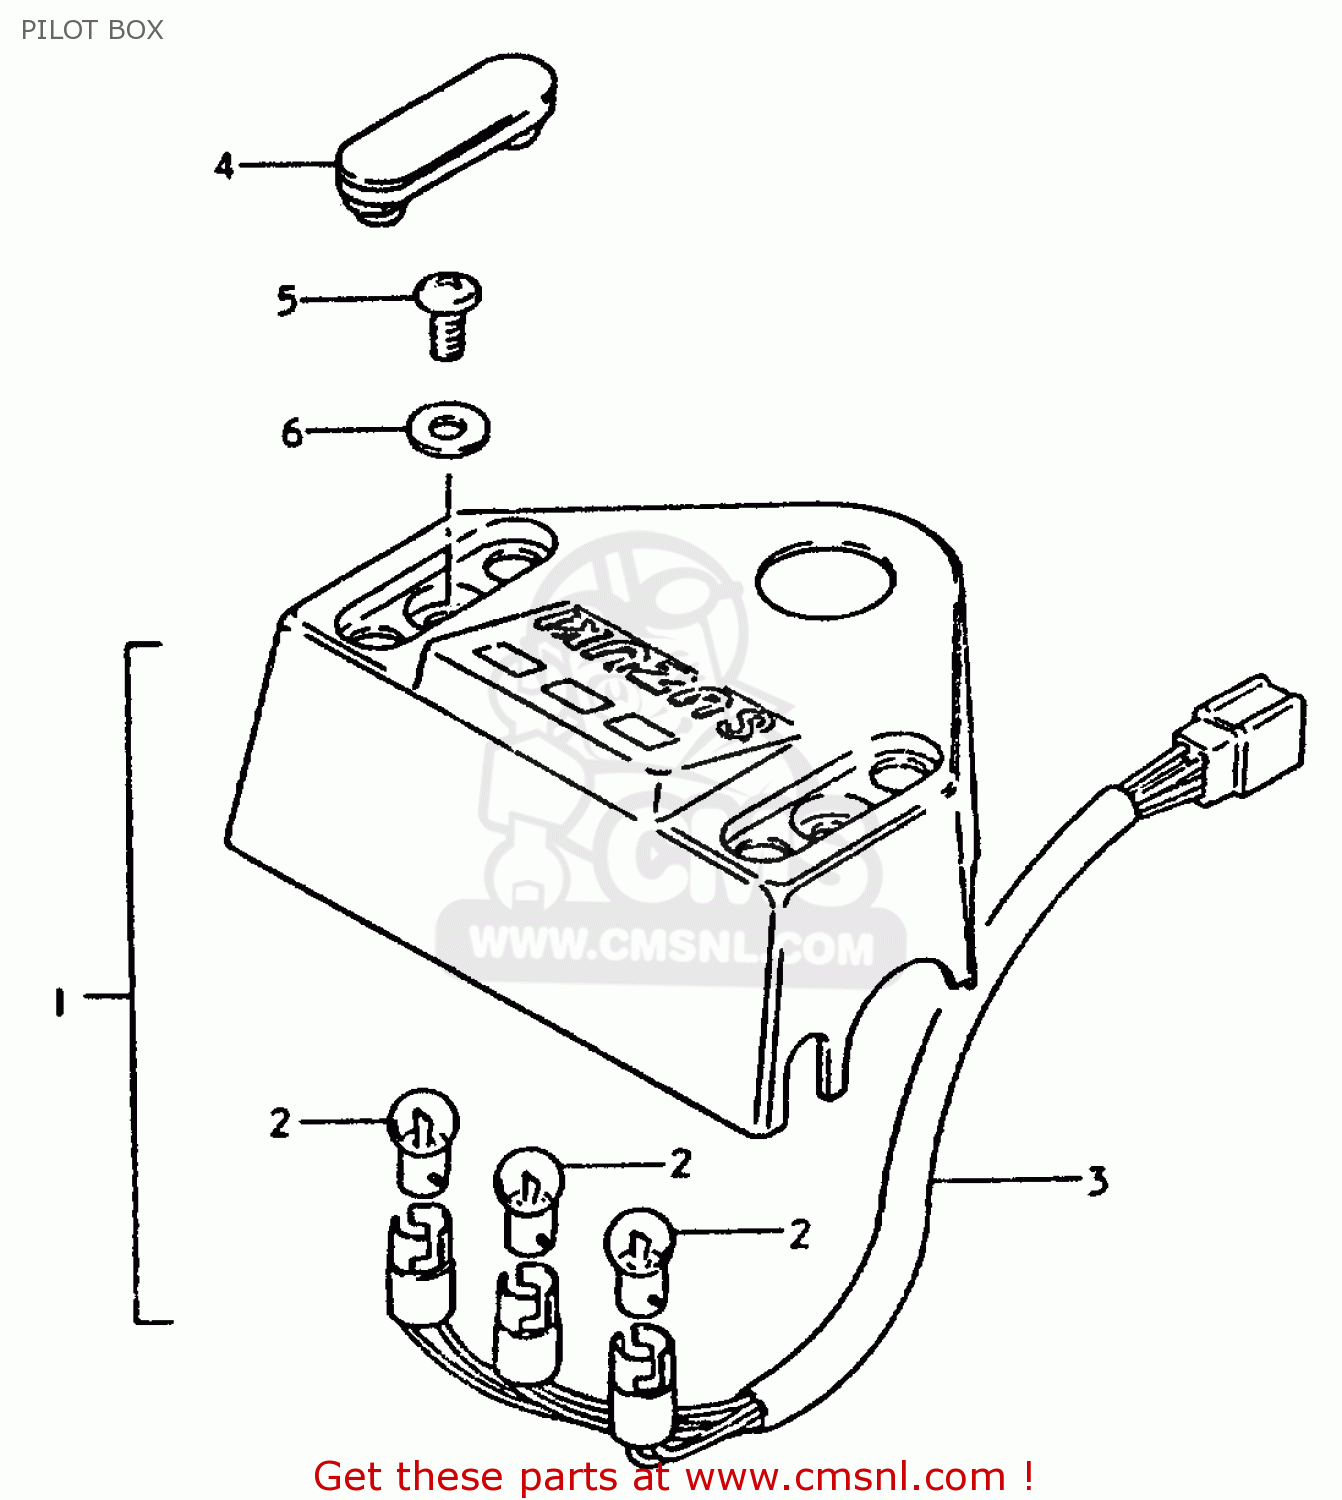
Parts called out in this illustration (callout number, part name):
1	PILOT BOX ASSY
2	BULB(6V/3W)
3	SOCKET
4	CAP,PILOT BOX BOLT
5	SCREW 6X12
6	WASHER
